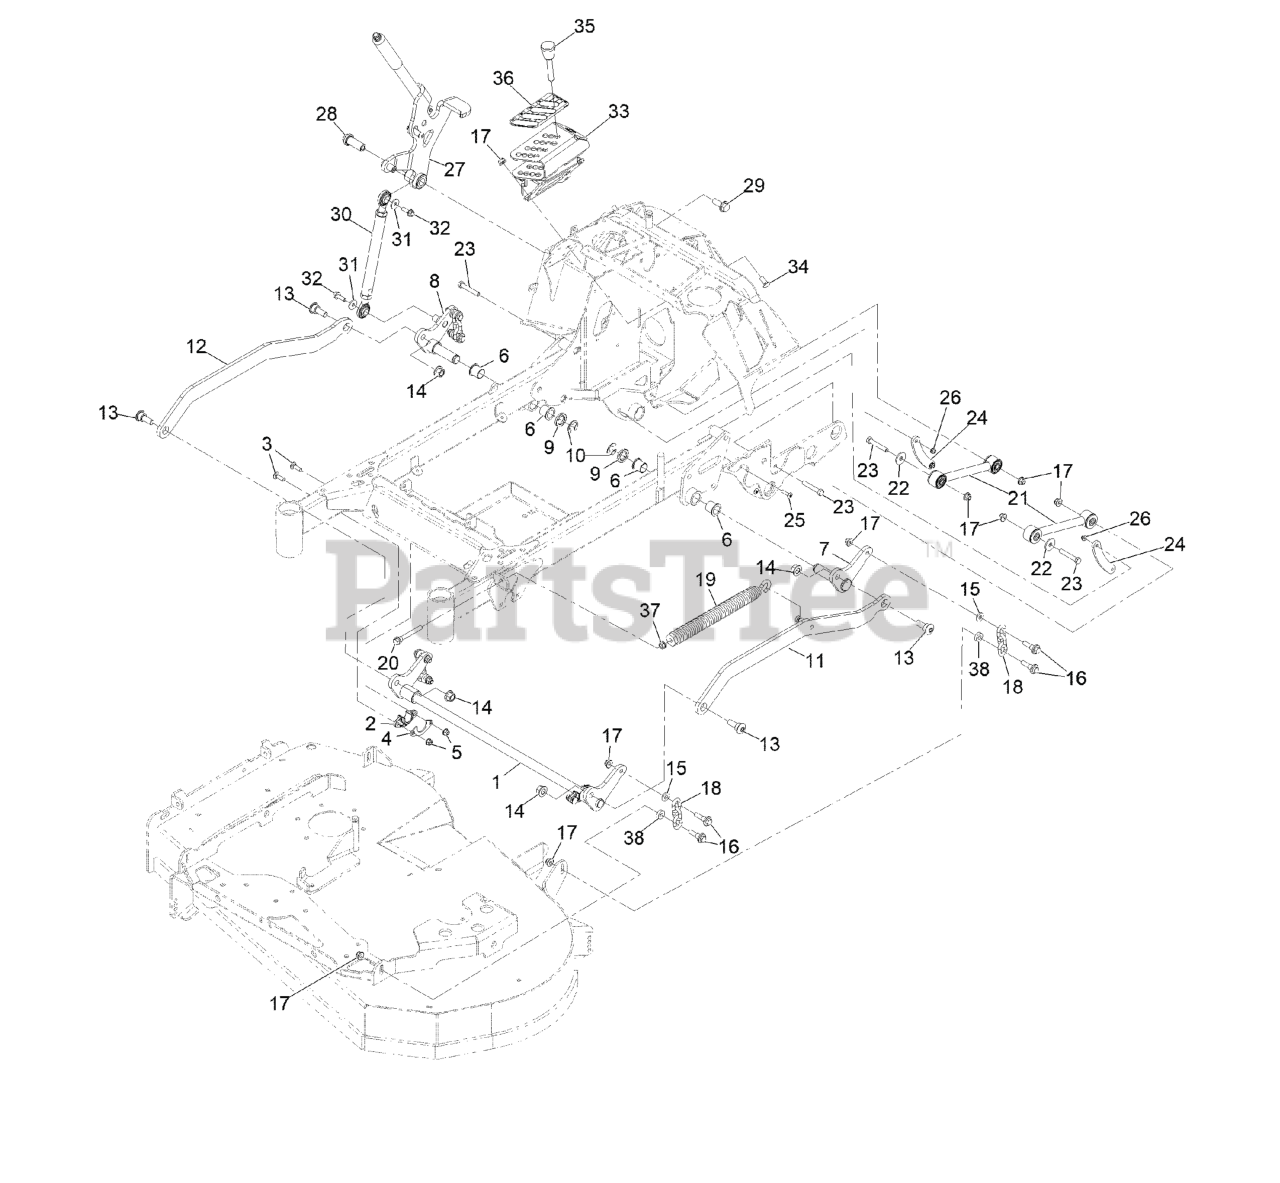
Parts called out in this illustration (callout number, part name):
1	WELD, HOC LIFT SHAFT
2	BUSHING-FLANGE
3	BOLT-CARR
4	GUSSET-LIFT, DECK
5	NUT-HF, NI
6	BUSHING, IGUS
7	WELD, BELLCRANK, LT RR
8	WELD, BELLCRANK, RT RR
9	SPACER, HOC PIVOT
10	RING-RETAINING, EXT
11	WELD, LIFT STRAP, LT
12	STRAP, LIFT RT
13	BOLT, SHOULDER
14	Nut-Lock 1/2-13
16	BOLT-SHOULDER
17	NUT-HF, NI
18	CHAIN-DECKLIFT
19	SPRING-EXTENSION
20	BOLT-SHOULDER
21	ASM, STRUT W/ BUSHINGS
22	WASHER
23	SCREW-HH
24	STRIP, RUB
25	SCREW-TTH
27	ASM, HOC LEVER
28	PIVOT, HOC LEVER
29	SCREW-HHF
30	ASM, LIFT ROD
31	WASHER-FRICTION
32	Screw-HHF
33	WELD, HOC INDEX
34	SCREW-CARR
35	PIN-HOC
36	DECAL-HEIGHT OF CUT
37	NUT-HHF, WHIZ
38	SPACER
